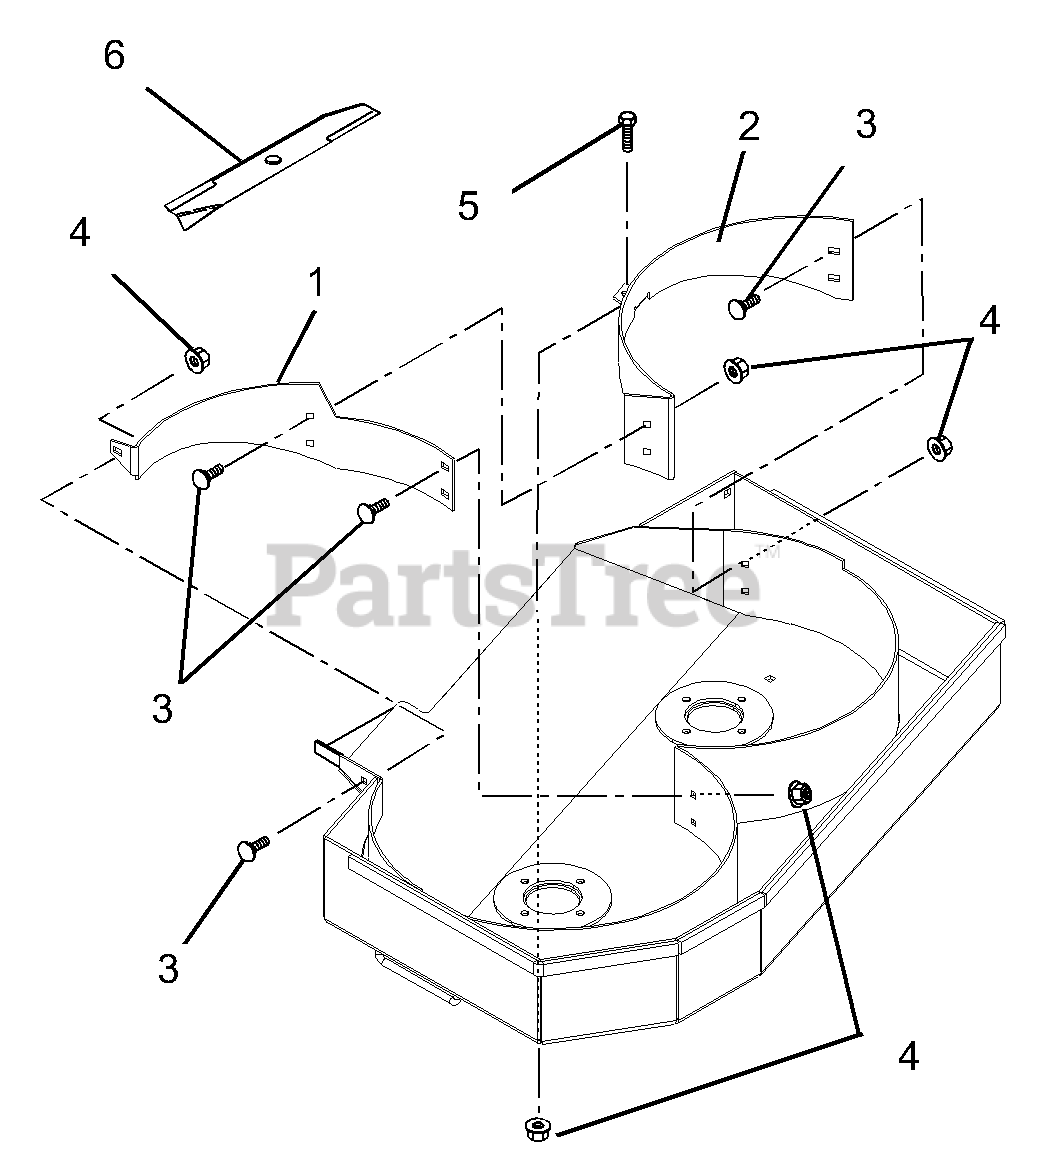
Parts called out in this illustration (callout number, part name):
1	32-Inch Left Mulch Baffle
1	Mulching Kit
1	36-Inch Left Mulch Baffle
2	32-Inch Right Mulch Baffle
2	Mulching Kit
2	36-Inch Right Mulch Baffle
3	5/16" x 3/4" Round Head Square Neck Bolt
3	Mulching Kit
4	5/16" Top-Locking Flange Nut
4	Mulching Kit
5	5/16" x 3/4" Hex Bolt
5	Mulching Kit
6	Mulching Blade
6	Mulching Kit
